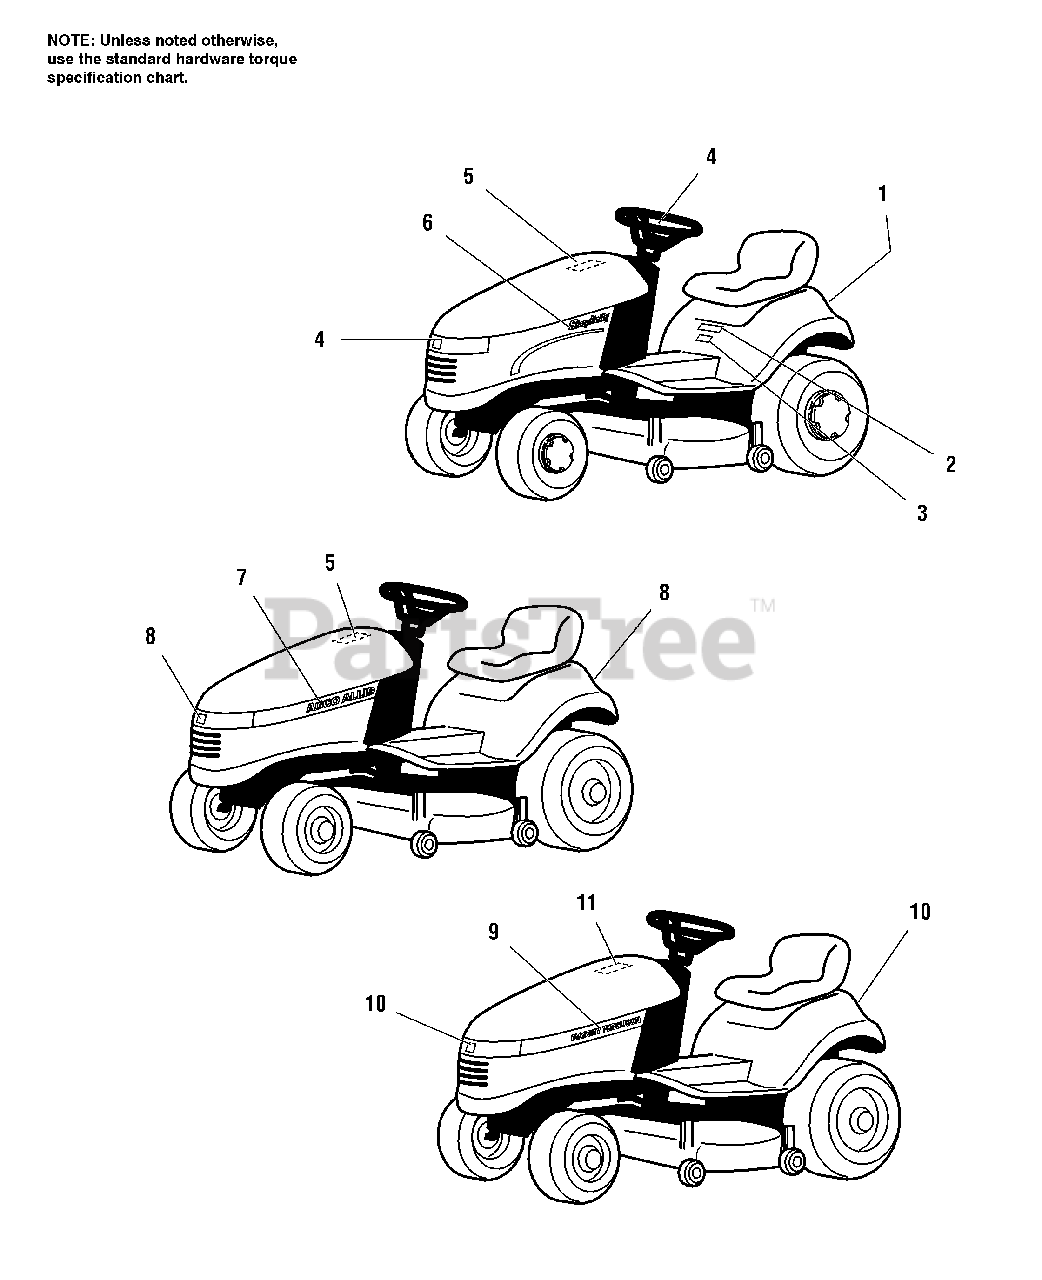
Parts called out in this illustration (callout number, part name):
1	DECAL, Seat Deck, Rear
2	DECAL, Seat Deck, Front
3	DECAL, Seat Deck, Front, 14-Hydro
3	DECAL, Seat Deck, Front, 14-Gear
3	DECAL, Seat Deck, Front, 16-Gear
3	DECAL, Seat Deck, Front, 16-Hydro
4	DECAL, Icon
5	DECAL, Hood (Underside), Touch-Up Paint
6	DECAL, Hood, Right
6	DECAL, Hood, Left
7	DECAL, Hood, Left, 514H
7	DECAL, Hood, Right, 514H
7	DECAL, Hood, Left, 514G
7	DECAL, Hood, Right, 514G
7	DECAL, Hood, Left, 516H
7	DECAL, Hood, Right, 516H
7	DECAL, Hood, Left, 516G
7	DECAL, Hood, Right, 516G
8	DECAL, Icon
9	DECAL, Hood, Left, 2514H
9	DECAL, Hood, Right, 2514H
9	DECAL, Hood, Left, 2514G
9	DECAL, Hood, Right, 2514G
9	DECAL, Hood, Left, 2516H
9	DECAL, Hood, Right, 2516H
10	DECAL, Icon
11	DECAL, Hood (Underside), Touch-Up Paint
